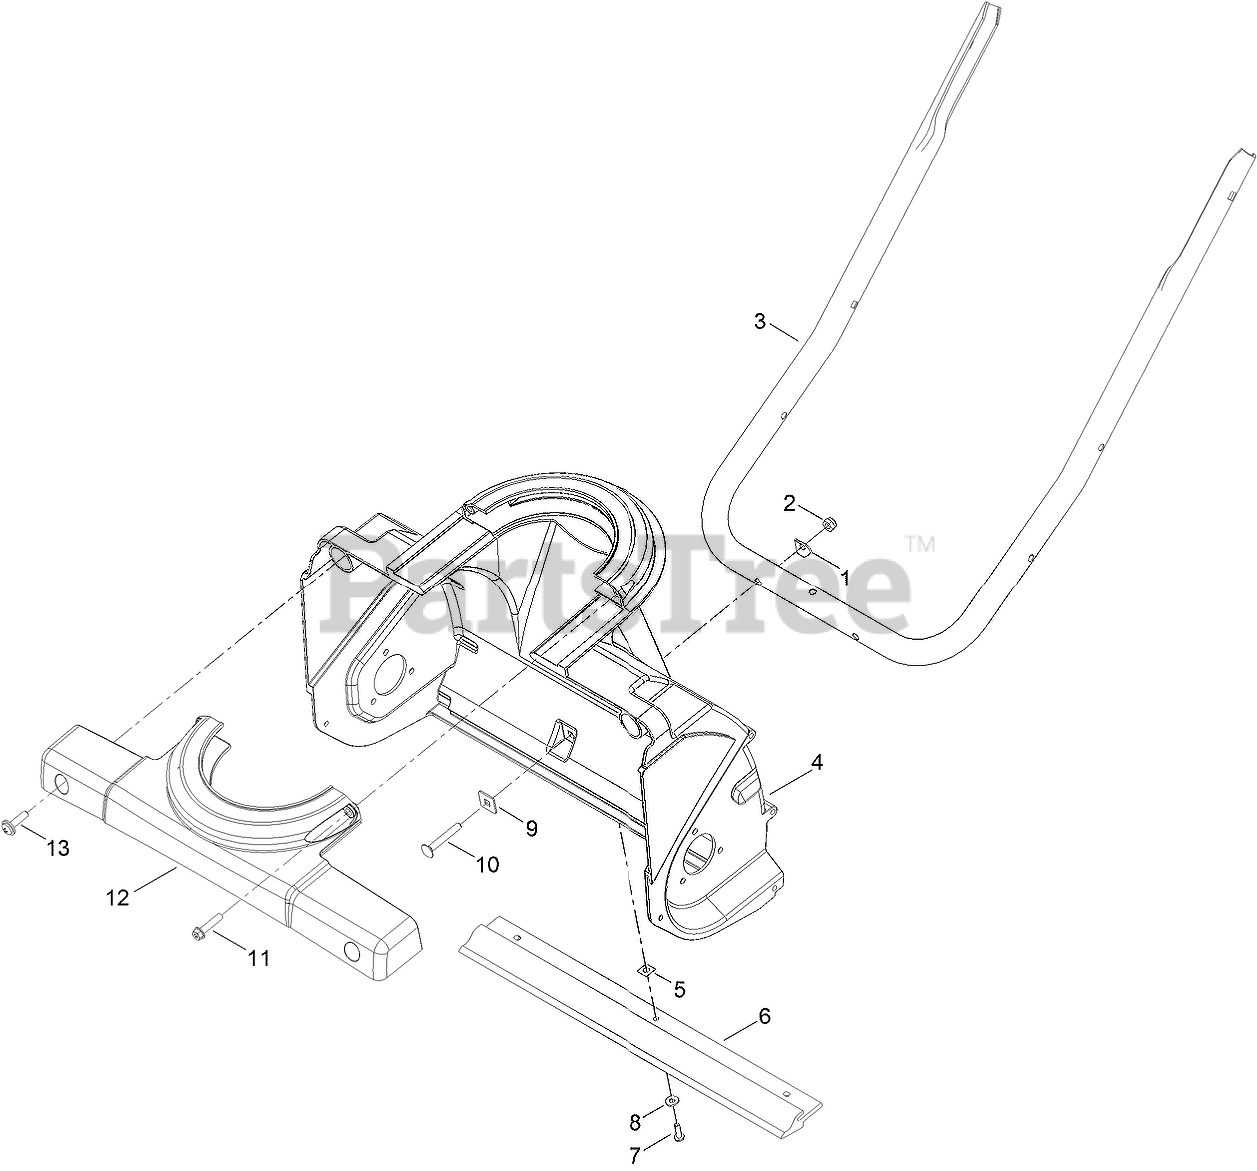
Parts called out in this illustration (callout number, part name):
1	WASHER
2	NUT-LOCK, NI
3	HANDLE-LOWER
4	HOUSING-LOWER
5	NUT-CLIP, U
6	SCRAPER
7	SCREW-HWHTF
8	WASHER-FLAT
9	WASHER-SQUARE
10	SCREW-CARR
11	SCREW-PLASTIC
12	RETAINER-CHUTE
13	SCREW-PPH
